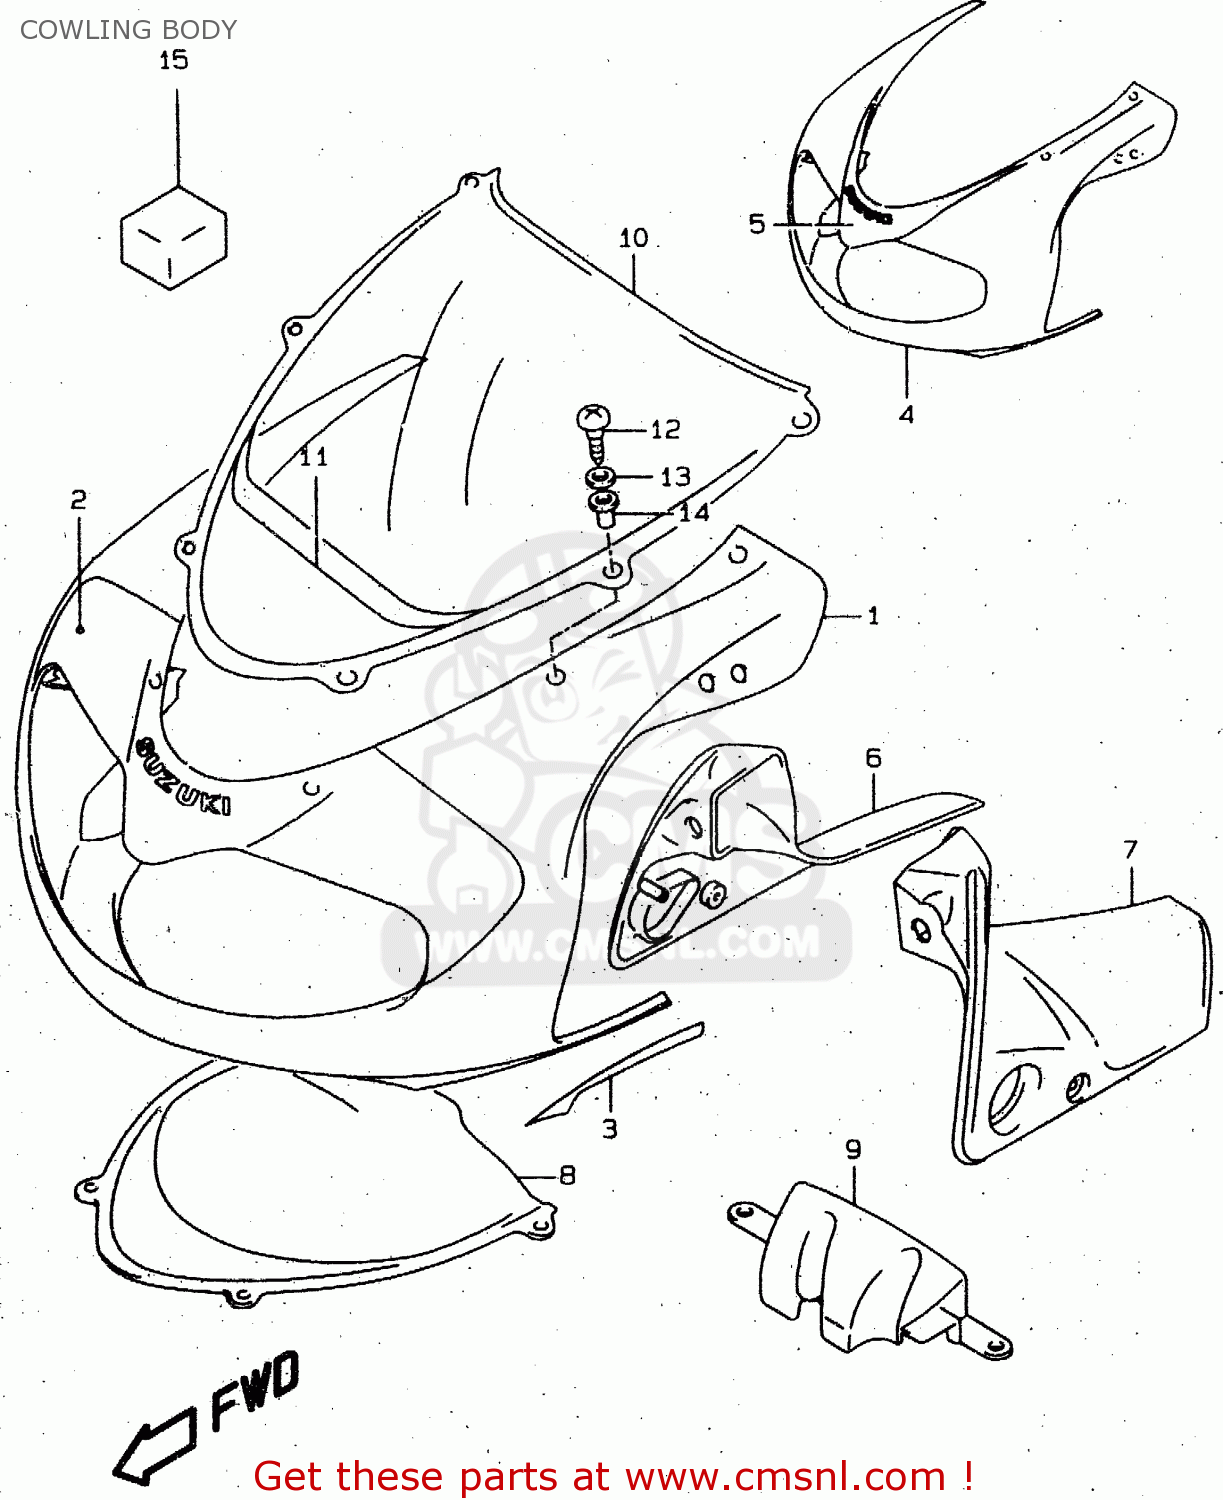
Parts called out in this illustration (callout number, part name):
1	COWLING ASSY,BODY(BLUE)
2	TAPE SET,BODY FR
3	TAPE SET,BODY SIDE(WHITE)
4	COWLING ASSY,BODY(YELLOW)
5	TAPE SET,BODY FR
6	PANEL,SIDE,R(BLACK)
7	PANEL,SIDE,L(BLACK)
8	COVER,BODY COWLING
9	COVER,COWLING FR LWR
10	WINDSCREEN
11	TAPE,WINDSCREEN
12	SCREW(5X14)
13	WASHER
14	NUT
15	CUSHION,BODY COWLING
